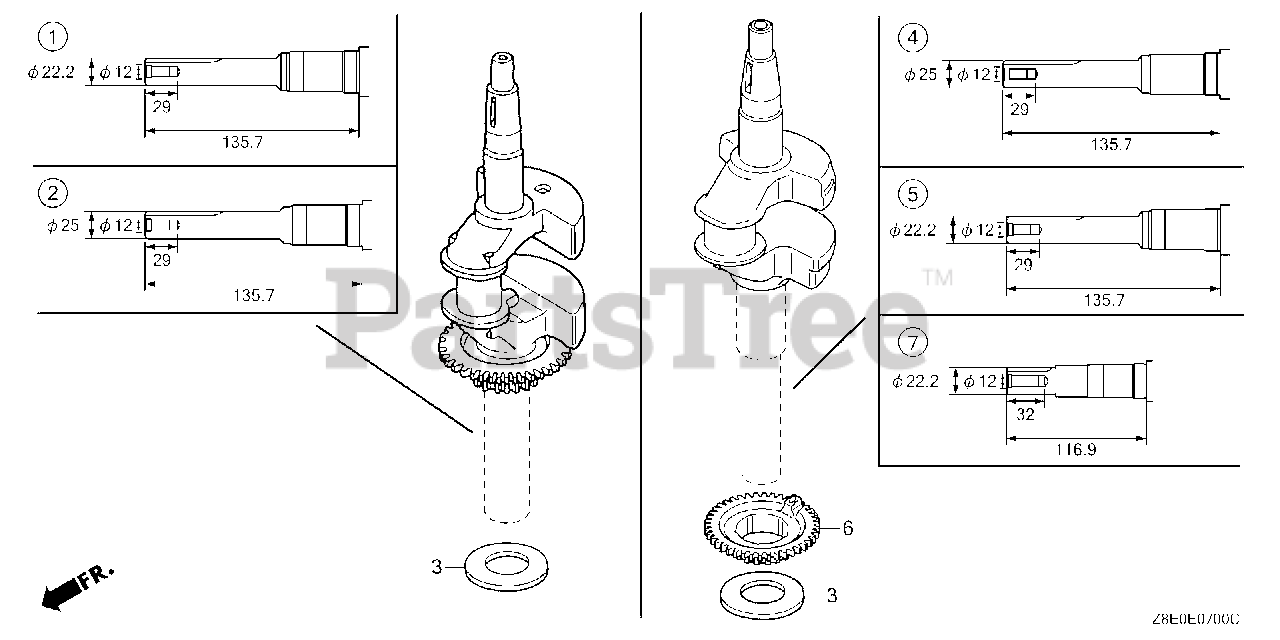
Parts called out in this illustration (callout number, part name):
2	CRANKSHAFT (USA)
3	WASHER, THRUST
4	CRANKSHAFT
6	PULLEY, TIMING BELT DRIVE
